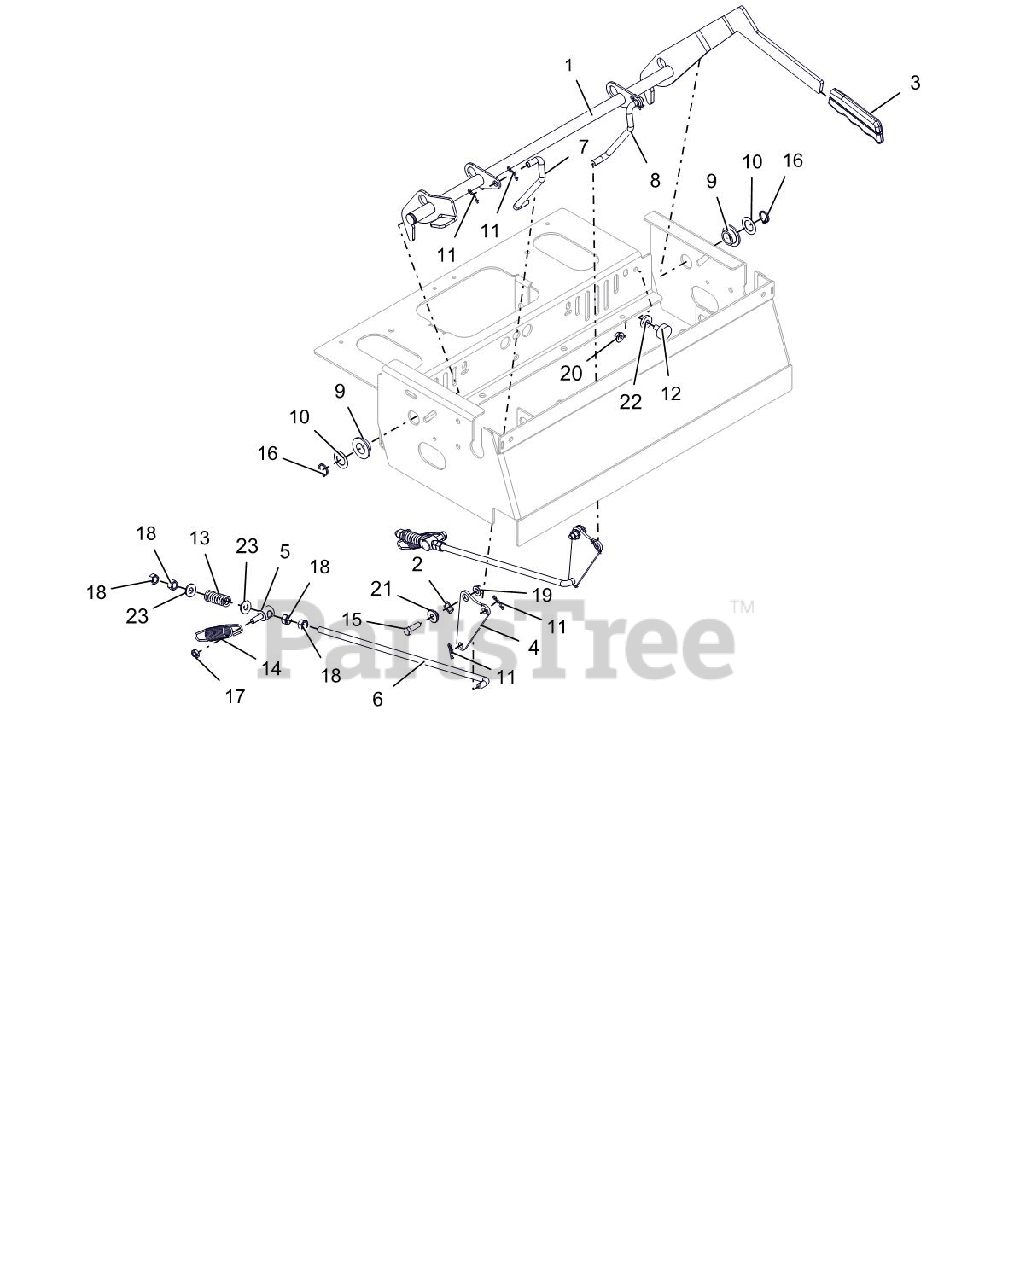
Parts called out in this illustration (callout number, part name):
1	WLDMT,PT200/400 PARK BRAKE-GAS
2	WAVE WASHER .531X.781X.125FH
3	GRIP, PARKING BRAKE (YELLOW)
4	PLATE, BRAKE PIVOT
5	TRUNNION, .38-16
6	ROD, BRAKE ADJ.
7	LINKAGE, RH BRAKE ACTUATING
8	LINKAGE, LH BRAKE ACTUATING
9	BSHG-FLG .762X1.48X.44 NYL
10	WSHR-HDND-THRST .758X1.23X.031
11	PIN-HAIR, ENDRIES #25 YWZC
12	BUMPER, RUBBER
13	SG-COMP .142 X .710 X 1.75
14	SPRING-TENS .105X.850X.4.880
15	@BLT-HEX .31-18X1.00 GR5 YWZC
16	RG-RTNG-EXT .689X.078
17	@NUT-LK-CTR-JAM .31-18 YWZC
18	@NUT-HEX .38-16 YWZC
19	@NUT-LK-TOP-FLG .31-18 YWZC
20	@NUT-SPNLK-FLG .312-18 YWZC
21	BSHG-FLG .32X.500X.344X.880
22	WSHR-FL-STL .328X.87X.179 YWZC
23	@WSHR-FL-STL.38X.875X.083 YWZC
